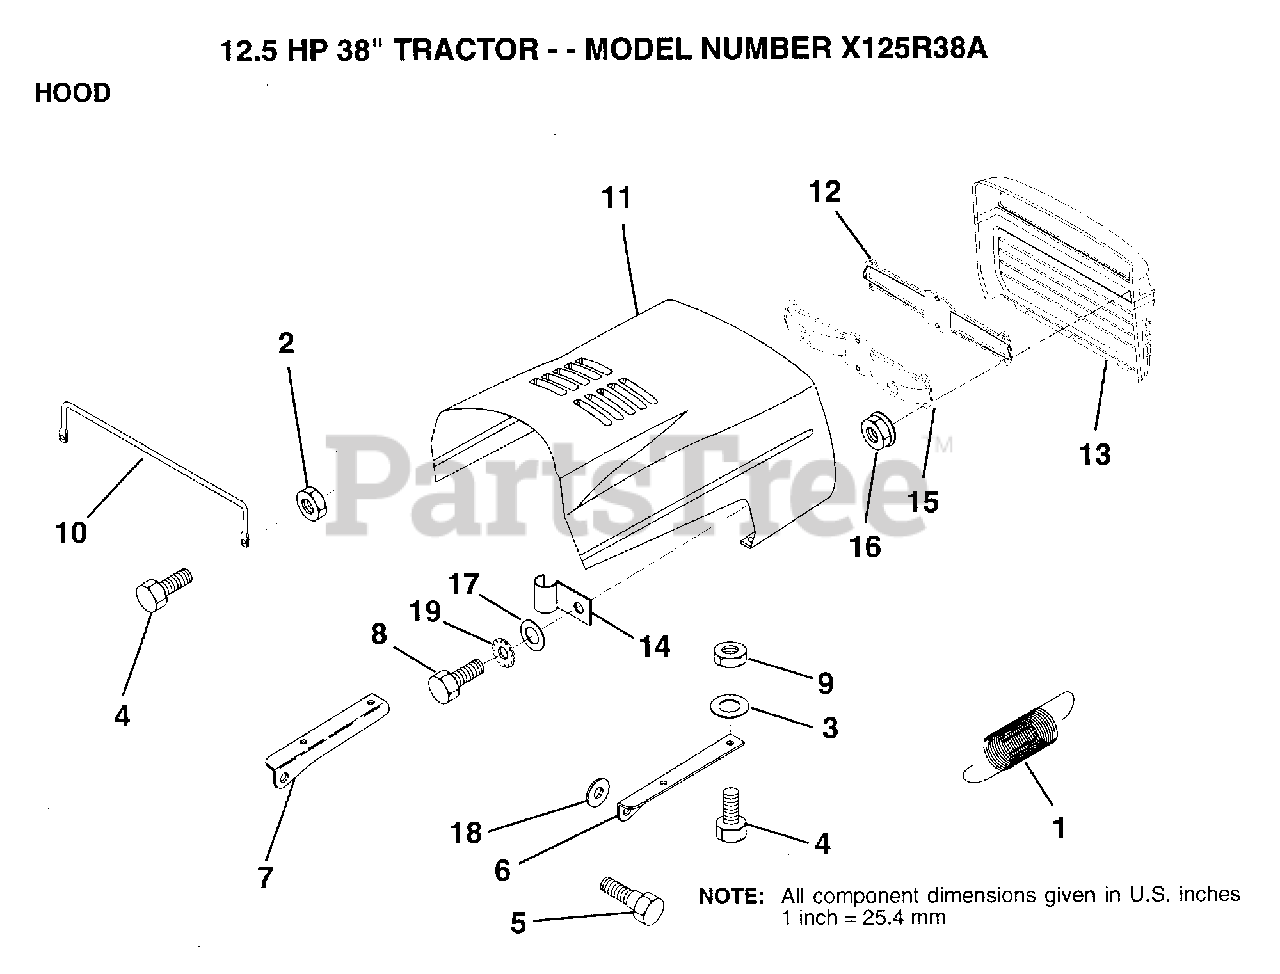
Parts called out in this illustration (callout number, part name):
1	EXT SPRING
2	NUT
3	WASHER
6	BRKT HOOD RH
7	BRKT HOOD LH
9	NUT
10	"BRACE,HOOD"
13	GRILL (BLACK)
14	CLIP T
16	NUT
17	WASHER
18	WASHER
19	LOCKWASHER GT
